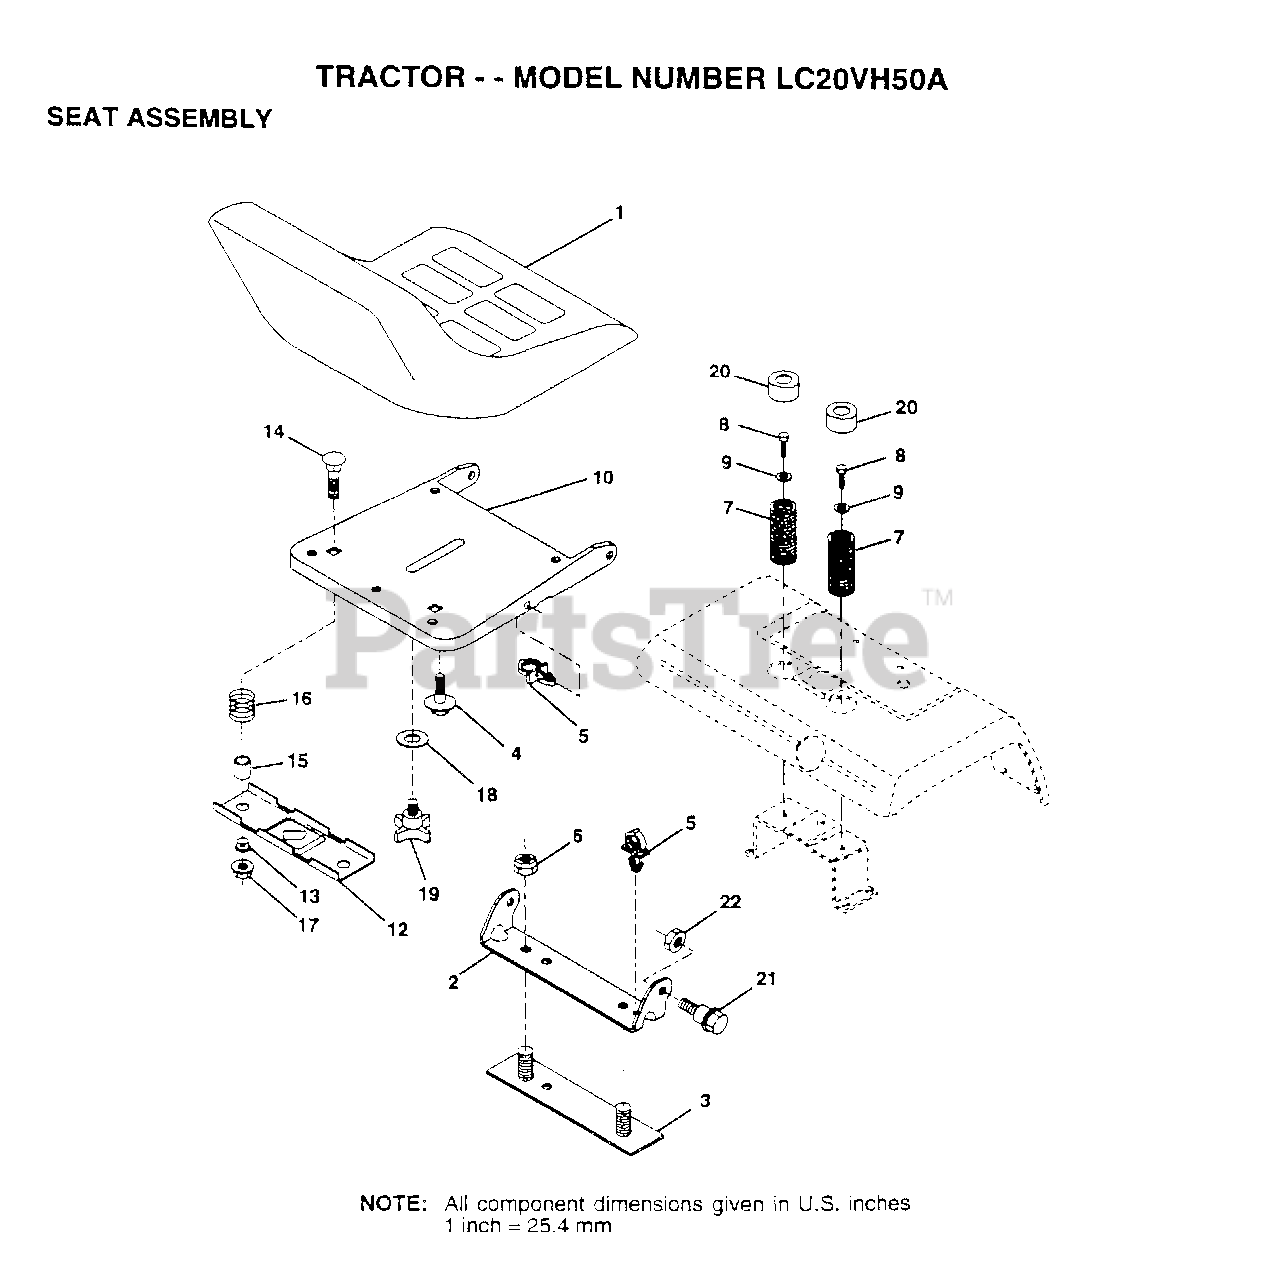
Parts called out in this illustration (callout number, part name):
2	BRACKET PVT SEAT
3	STRAP ASM FENDER
4	"BOLT,SHOULDER"
5	CLIP.PUSH-IN.HING
7	SPRING COMPRESSIO
8	SCREW LT
9	WASHER
12	BRKT SWITCH
13	BUSHING
15	SPACER SPLIT
16	SPRING COMPRESSED
18	WASHER
19	"KNOB 1/2"" YT"
20	CAP SPRING
21	BOLT.SHLD.5/16-18
